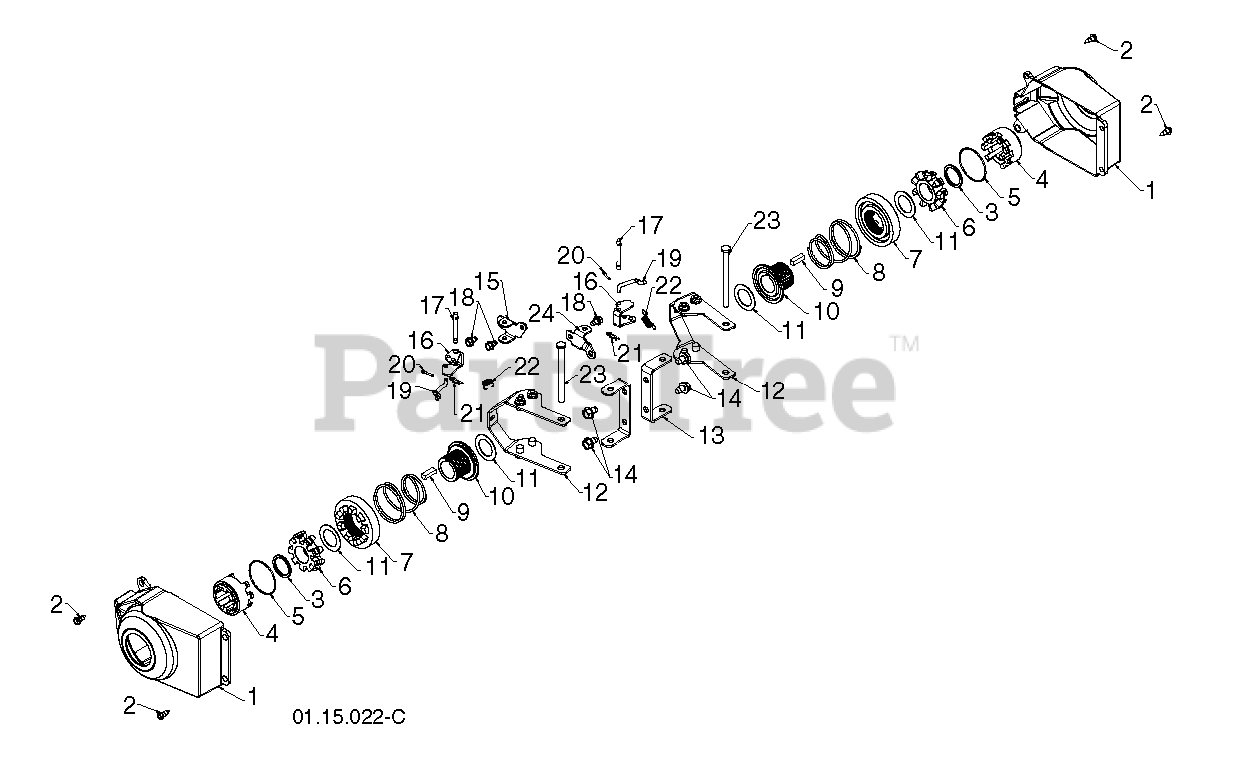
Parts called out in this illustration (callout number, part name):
1	COVER, POWER STEERING
2	SCREW, HEX HEAD, TAPPING
3	SPACER.POWER.STEERING TRACK
4	DRIVER.WHEEL.POWER.STEERING
5	RING, WIRE RETAINER
6	LOBE WHEEL
7	SLIDE.CLUTCH.SNOW
8	SPRING COMPRESSION TAPERED.PS
9	KEY, SQUARE 1/4 X .875
11	WASHER 1.00
12	YOKE.ASM.BOLT.BLACK
13	BRACKET.STEER.PNT.BLACK
14	Screw 5/16-18 x 1/2 Hex, Self Tapping 5/16-18 x 1/2
15	BRKT.STEER.PIVOT.RH
16	BELLCRANK.STEER
17	PIN, STEERING BELLCRANK
18	SCREW 1/4X20
19	LINK.STEER.YOKE
20	RETAINER CLIP
21	RETAINER CLIP PM
22	SPRING LATCH
23	PIN, STEERING LEVER
24	BRACKET.STEER.PIVOT.LH.YZ
